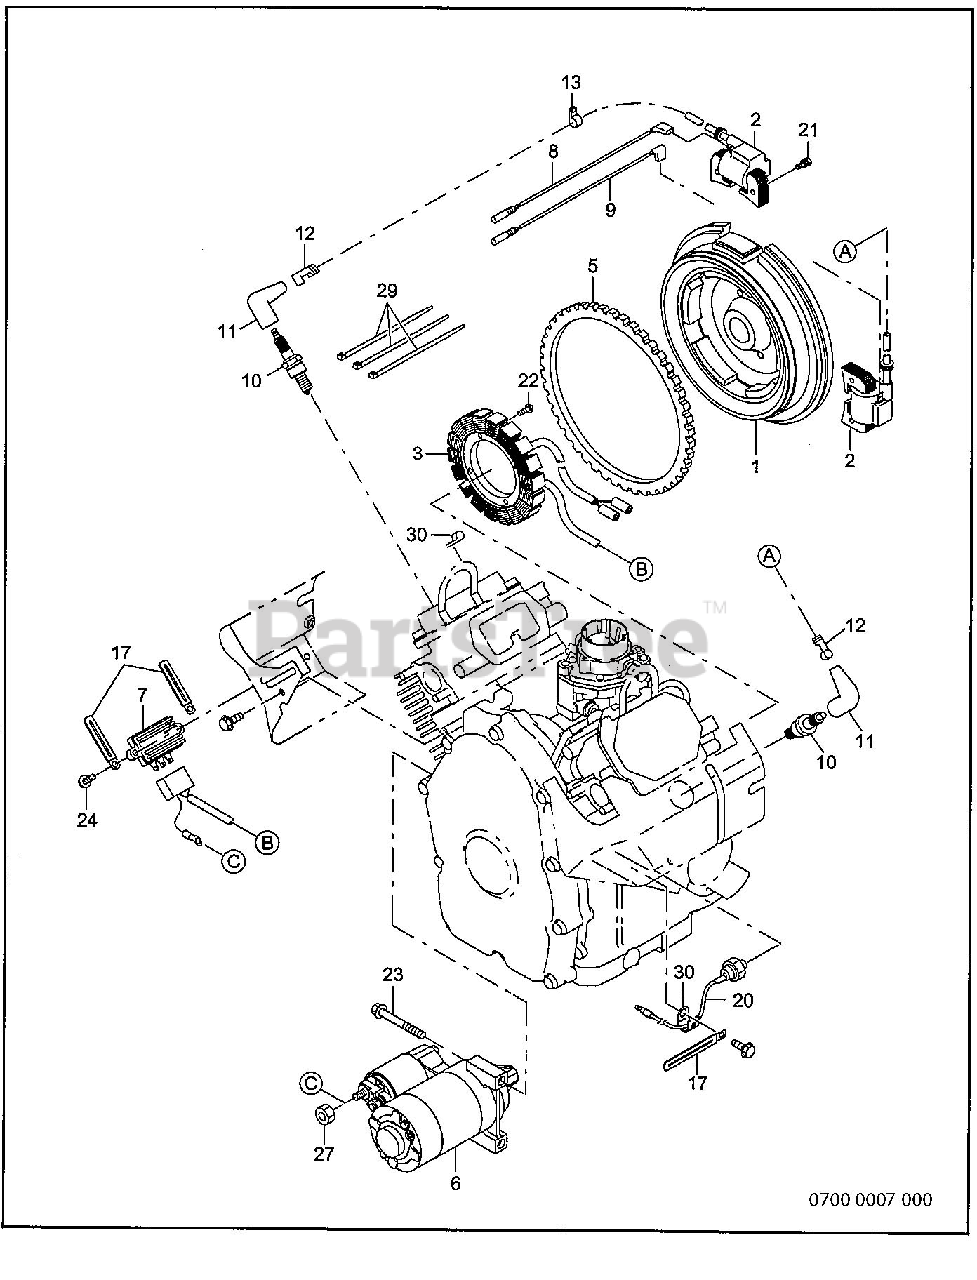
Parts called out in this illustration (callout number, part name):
2	IGNITION COIL ASSY
3	CHARGE COIL ASSY
6	STARTING MOTOR ASSY
7	REGULATOR ASSY
10	SPARK PLUG (BPR6ES)
11	SPARK PLUG CAP
20	WIRE ASSY, oil pressure switch
21	BOLT and WASHER ASSY
22	SCREW and WASHER ASSY
23	FLANGE BOLT
24	FLANGE BOLT
